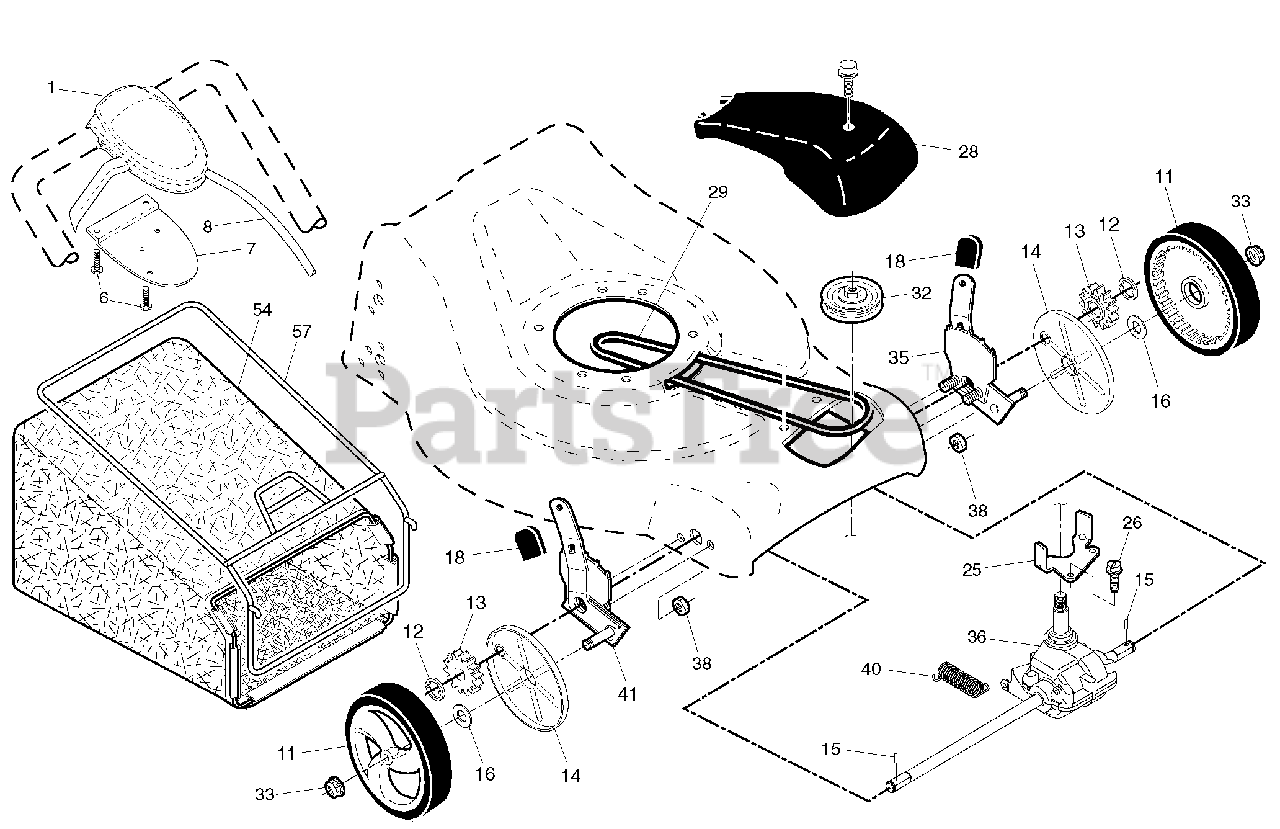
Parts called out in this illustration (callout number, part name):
6	SCREW, PHILLIPS HEAD 10 X 5/8
7	BRACKET.DRIVE.CONTROL.MOUNT
8	CABLE ASSEMBLY, DRIVE
12	E-RING 7/16 RE
13	PINION.14.TEETH.FGD
14	Inner Wheel Dust Cover
15	PAWL, DRIVE
16	WASHER FLUT
18	SELECTOR KNOB
25	BRACKET.BELT.GUIDE.22+FGD.BZP
29	BELT.DRIVE.FG
32	PULLEY.DRIVE.EZ/VARI.SCREWON
33	NUT.HEX.FLANGE.3/8-16.LOCKNUT
35	KIT ADJUSTER ASM.438151.LT
36	TRANSMISSION.21.FGD.HT.VST
38	LOCKNUT
41	KIT ADJUSTER ASM.438148 .RT
57	FRAME.GBAG.21.FWGD
